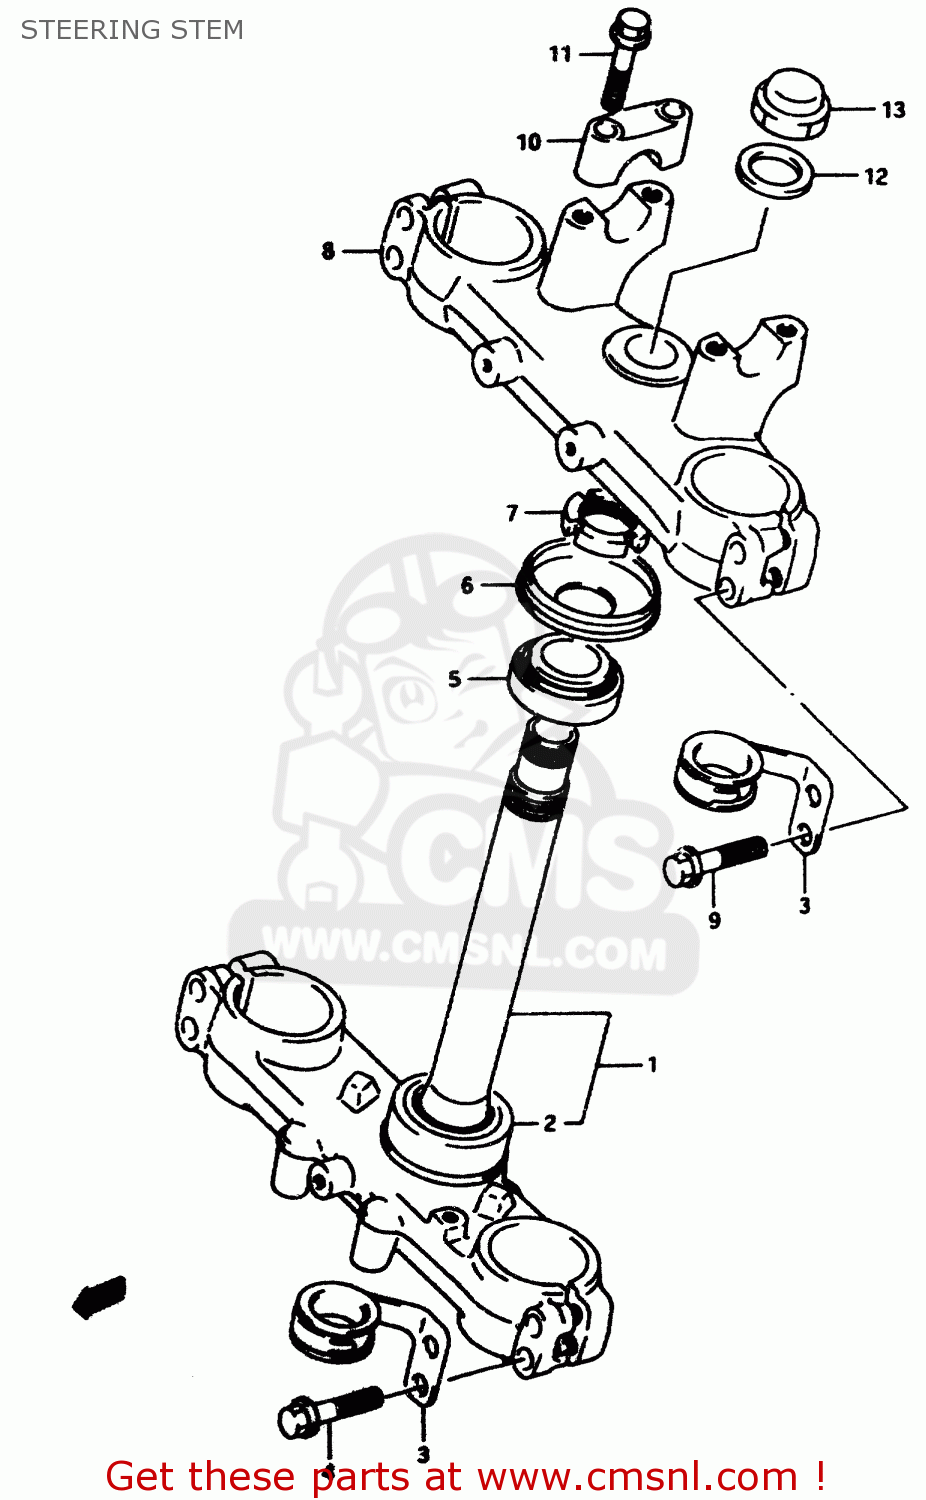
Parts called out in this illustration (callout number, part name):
1	STEM,STEERING
2	BEARING(30X55X17)
3	GUIDE,CABLE LWR,L
4	BOLT
5	BEARING(25X47X15)
6	SEAL,STEERING UPR DUST
7	NUT,STEERING STEM
8	HEAD,STEERING STEM
9	BOLT
10	HOLDER,HANDLE UPR
11	BOLT
12	WASHER
13	NUT,CAP
14	BRACKET,FRONT SIDE REFLECTOR
15	BRACKET,FR SIDE REFLECTOR,L
